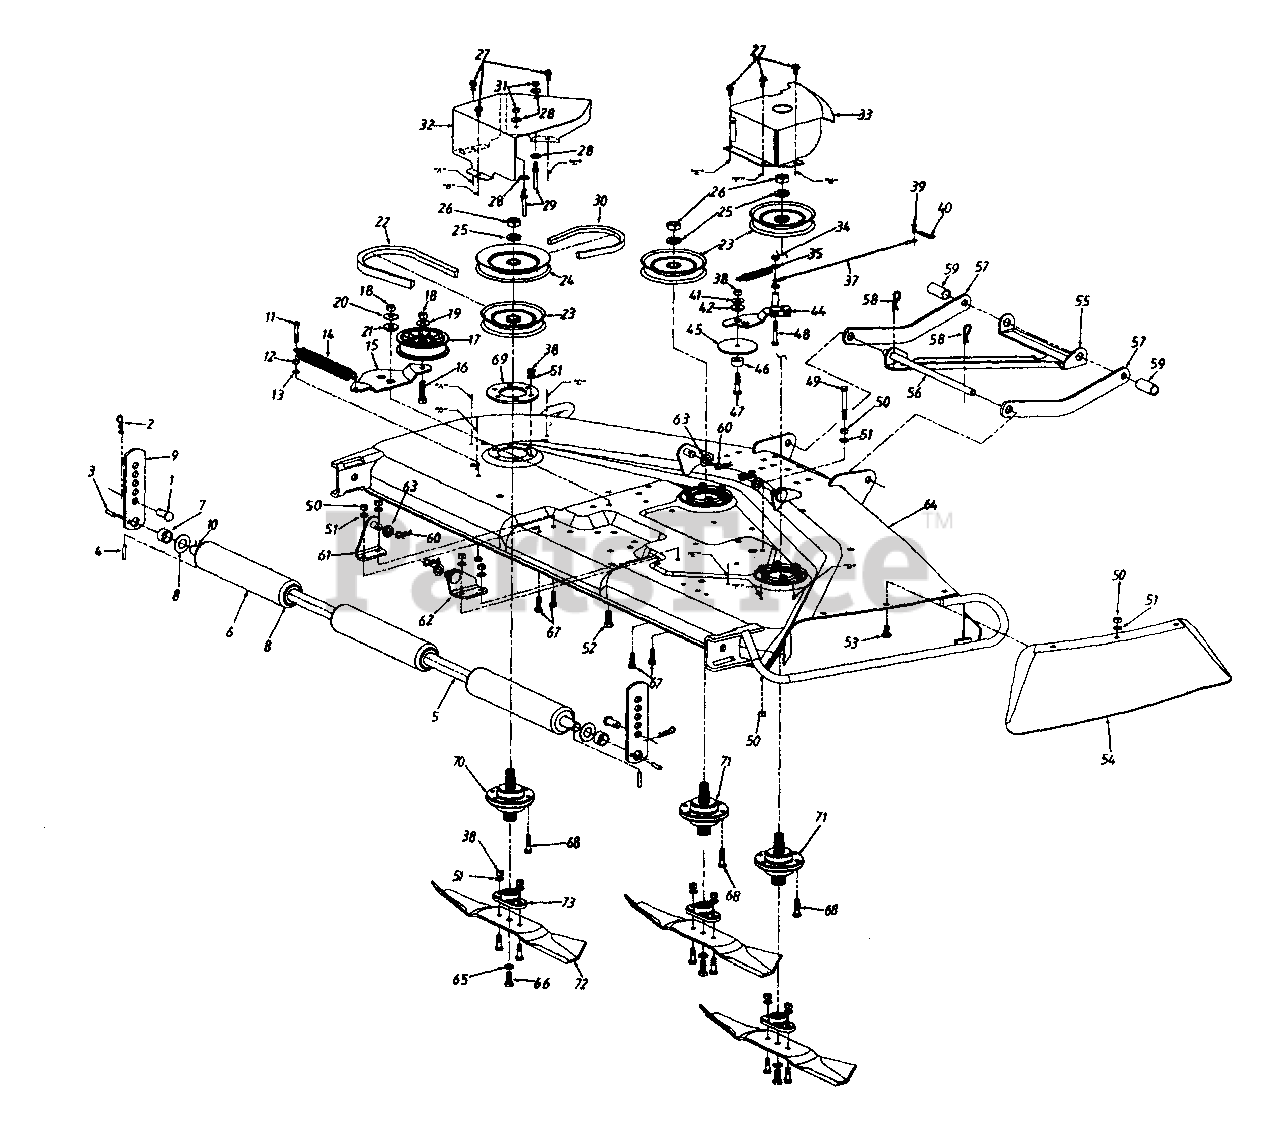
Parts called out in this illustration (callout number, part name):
2	Hairpin Clip
3	Spring Pin 1/4" x 1" Lg.
4	Spring Pin 3/16" x 1-1/4" Lg.
7	Spacer .75" I.D.
8	Fl-Wash. .76" I.D. x 1.5" O.D.
10	Roller Shaft
11	Hex Bolt 1/4-28 x 1.5" Lg. (Gr. 5)
12	Hex Nut 1/4-28 Thd.
13	L-Wash. 1/4" I.D.
14	Ext. Spring 7.33" Lg.
17	Idler Pulley
18	Hex Nut 3/8-24 Thd.
19	Bell-Wash. 3/8" I.D.
20	Bell-Wash. .39" I.D. x 1.13" O.D.
21	Shld. Spacer .625" I.D.
22	"V"-Belt
24	Upper Deck Pulley
25	L-Wash. 5/8" I.D.
26	Hex Jam Nut 5/8-18 Thd.
27	Hex Wash. Hd. Scr. 1/4-20 x .5" Lg.
28	Bell-Wash. 1/4" I.D.
29	Belt Guard Pin
30	"V"-Belt
31	Hex Nut 1/4-20 Thd.
35	Ext. Spring 3.97" Lg.
38	Hex Nut 5/16-24 Thd.
39	Clevis Pin
40	Hairpin Clip
41	Bell-Wash. .325" I.D.
42	Shld. Spacer
44	Brake Ass'y.
45	Fl-Wash. 5/16" I.D. x .3" O.D.
46	Spacer .44" Lg.
47	Hex Bolt 5/16-24 x 1.5" Lg. (Gr. 5)
48	Hex Bolt 1/4-28 x 1.75" Lg. (Gr. 5)
49	Hex Bolt 5/16-18 x 2.5" Lg.
50	Hex Nut 5/16-18 Thd.
51	L-Wash. 5/16" I.D.
52	Hex Bolt 3/8-24 x 1" Lg.
53	Carr. Bolt 5/16-18 x .75" Lg.
59	Spacer 1.75" Lg.
60	Hairpin Clip
61	Deck Hanger Brkt. - L.H.
62	Deck Hanger Brkt. - R.H.
63	Fl-Wash. 1/2" I.D. x .93" O.D.
66	Hex Bolt 3/8-24 x .88" Lg. (Gr. 5)
67	Hex Bolt 5/16-18 x 1" Lg.
68	Hex Bolt 5/16-24 x 1-1/4" Lg. (Gr. 5)
69	Spindle Reinforcement Plate
70	Spindle Ass'y. (L.H.)
71	Spindle Ass'y. (R.H. & Center)
72	Blade
73	Blade Adapter
